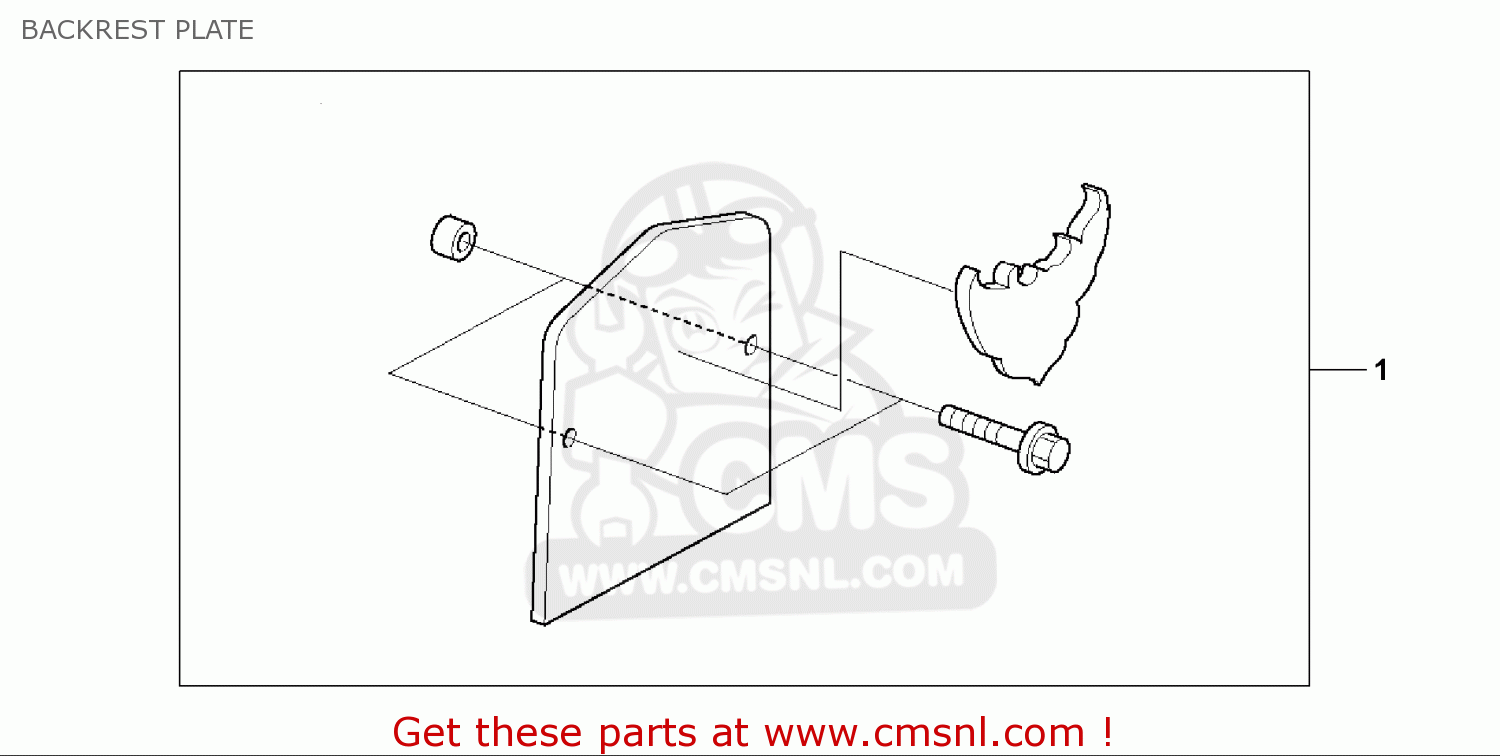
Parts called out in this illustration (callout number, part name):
1	BACKREST PLATE
2	COLLAR,CABLE CLAM
3	BOLT,FLANGE,6X22
